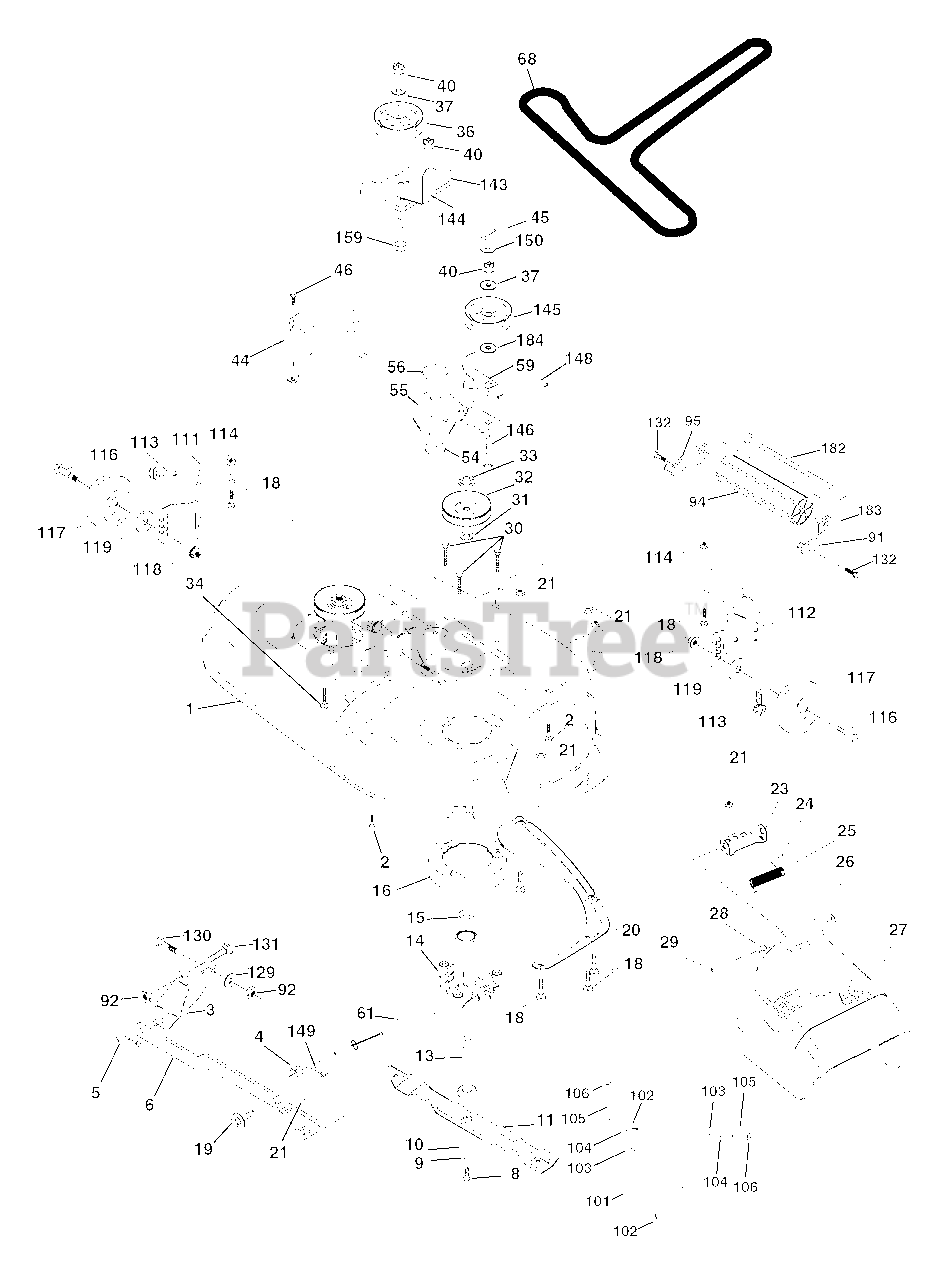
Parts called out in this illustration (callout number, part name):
1	Mower Deck Assembly, 42"
2	Bolt
3	Bracket Assembly,Sway Bar, Front
4	Bracket Sway Bar 42" Deck
5	Retainer Spring
6	Bar Sway Deck
8	Bolt, Hex 3/8-24 x 1.25 Gr. 8
9	Washer, Lock
10	Washer, Hardened (The following blades are available)
11	Blade, Mulching 42 Std
11	Blade Mulching 42 Premium
11	Blade Mower 42 Hi-Lift
13	Shaft Assembly, Mandrel, Vented
14	Housing, Mandrel, Vented
15	Bearing, Ball, Mandrel
18	Bolt, Carriage 5/16-18 x 5/8
19	Bolt, Shoulder
20	Baffle, Vortex
21	Nut Crownlock 5/16-18 UNC
22	Stiffener Bracket
23	Bracket, Deflector
24	Cap, Sleeve
25	Spring, Torsion, Deflector
27	Shield, Deflector
28	Washer 11/32 x 5/8 x 16 Ga.
29	Rod, Hinge
30	Screw Thdrol Hex
31	Washer, Spacer
32	Pulley, Mandrel
33	Nut, Toplock, Flanged
36	Pulley, Idler, Flat
37	Washer 13/32 x 13/16 x 16 Gauge
40	Nut Crownlock 3/8-16 UNC
44	Guard, Mandrel, L.H.
45	Retainer
46	Screw, Thd. Roll 1/4-20 x 5/8
54	Washer, Hardened
55	Arm, Idler
56	Spacer, Retainer
59	Guard, TUV Idler
61	Spring Ext Elect Clutch 42" Dck
91	Bracket Asm Noseroller Lh
92	Nut Lock Hex 5/16-18
94	Roller Nose 38-50
95	Bracket Asm Noseroller Rh
101	Mulcher Cover
102	Screw
103	Washer #10
104	Washer, Lock
105	Latch Assembly, Bagger
106	Nut, Weld
111	Bracket Wheel Guage LH
112	Bracket wheel Guage RH
113	Screw 5/16-18 x 5/8 Tap R
114	Nut Keps 5/16-18
116	Bolt, Shoulder
117	Wheel, Gauge
118	Nut, Centerlock 3/8-16
119	Washer 3/8 x 7/8 x 14 Gauge
129	Washer 13/32 x 13/16 x Ga.
130	Bolt Fin Hex 3/8-16unc x 1 Gr.5
131	Bolt Rdhd Sqnk 3/8-16unc x 1
132	Screw 3/8-16 x .75
143	Bracket Arm Idler 42"
144	Keeper Belt 42" Clutch Cable
145	Pulley Idler Flat
146	Bolt Carriage Idler
148	Spring Return Idler
149	Retainer Spring Yellow Zinc
150	Washer 9/32 x 3/4 x 16 Ga.
159	Bolt Rdhd Sqn 3/8-16 UNC x 1- 3/4
182	Rod Roller Nose
183	Retainer Spring
184	Washer 13/32 x 7/8 x 10 Ga.
